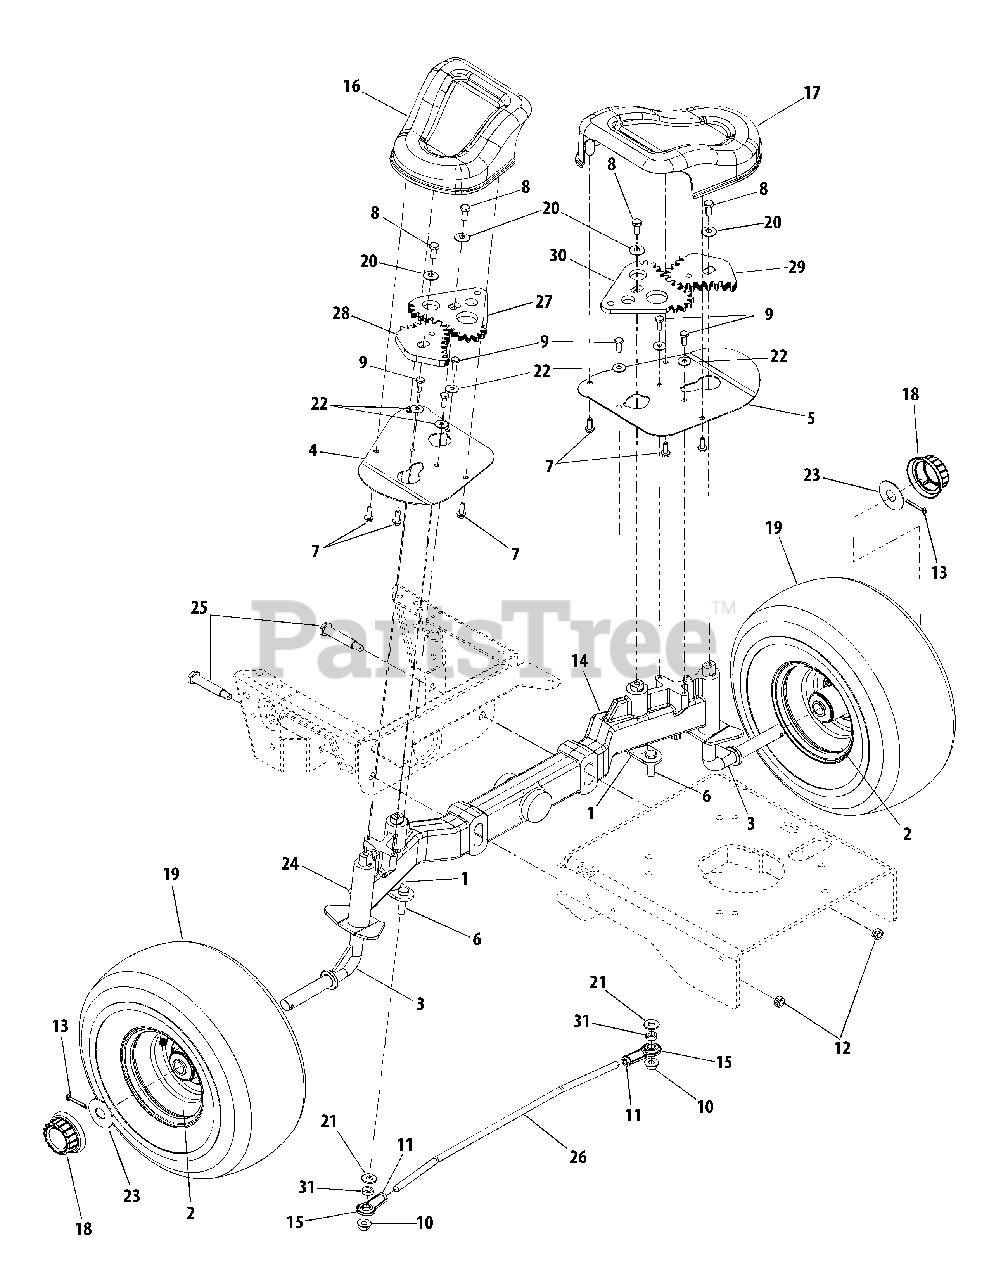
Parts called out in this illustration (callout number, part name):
1	Shaft Assembly, Steering Pivot
2	Ball Bearings
2	Air Valve.
2	Lube Fitting
3	Axle Assembly, Wheel
7	Screw, Hex Wash. Hd., 1/4-15 x .75
8	Screw, Hex Cap, 5/16-18 x .75 Gr5 Patch
9	Screw, Hex Cap, 1/4-20 x .75 Gr5
10	Nut, Hex Flange Insert Lock, 3/8-16 GrF
11	Nut, Hex Jam, 3/8-24 Gr5
12	Nut, Hex Center Lock, 3/8-16 GrB
13	Pin, Cotter, 5/32 x 1.25
14	Bar, Pivot
15	Ball Joint End, .375
16	Cover, Steering Gear, RH
17	Cover, Steering Gear, LH
18	Hubcap
19	Tire
20	Washer, Belleville, .34 x .872 x .06
21	Washer, Flat, .385 x .87 x .092
22	Washer, Belleville, .265 x .75 x .062
23	Washer, Flat, .755 x 1.92 x .060
24	Fitting, Lube, 3/16 drive
25	Bolt, Shoulder, .5 x 2.23 : 3/8-16
26	Rod, Tie, 3/8-24 x 18.27
27	Gear, Spur, 13T RH
28	Gear, Spur, 14T RH
29	Gear, Spur, 14T LH
30	Gear, Spur, 13T LH
31	Spacer, .38 x .625 x .265
